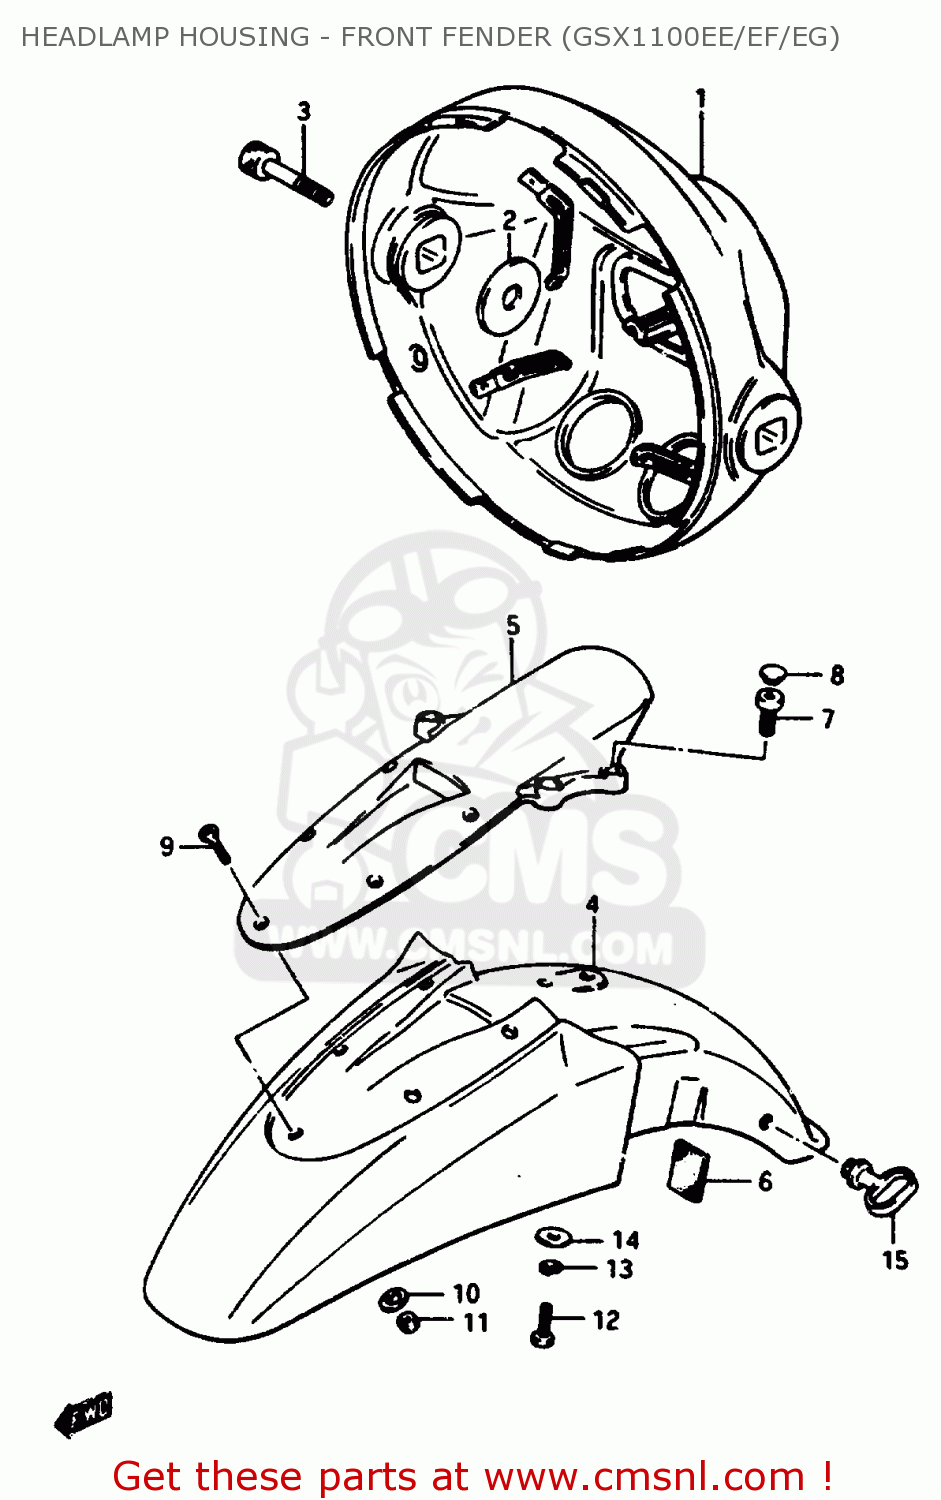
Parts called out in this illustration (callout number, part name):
1	HOUSING,HEADLAMP(BLACK)
2	WASHER (8.5X29X1.6)
3	BOLT, LH
4	FENDER,FRONT
5	BRACE,FR FENDER CTR
6	CUSHION
7	BOLT
8	CAP(OD:14.5)
9	SCREW, CENTER
10	WASHER
11	NUT 8MM
12	BOLT, UPPER
13	LOCK WASHER
14	WASHER
15	GUIDE,CABLE
